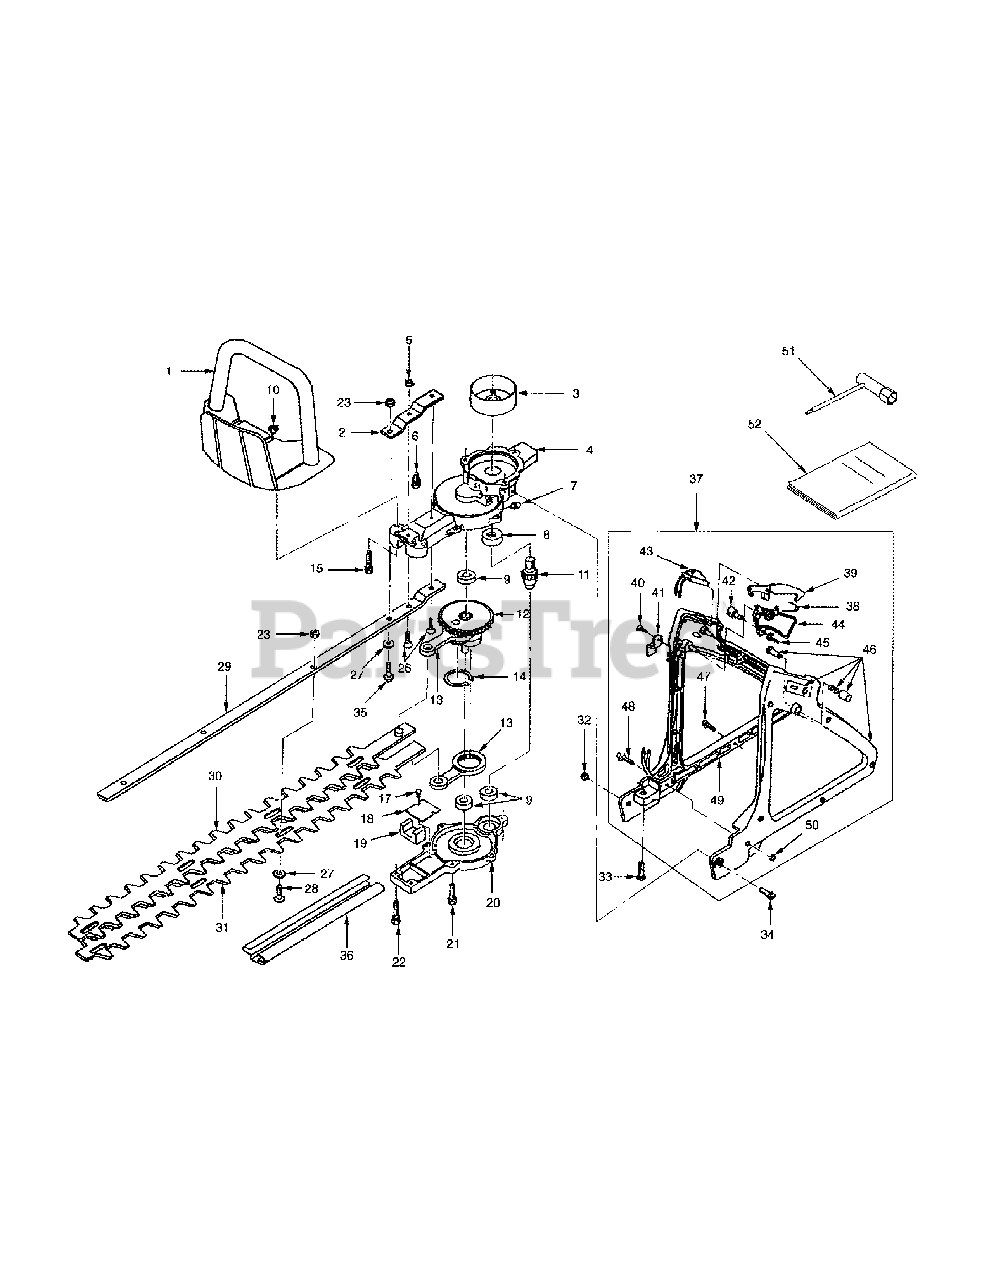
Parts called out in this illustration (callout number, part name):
3	Drum, Clutch
7	Nipples, Grease
8	Bearing, Ball, 6001
9	Bearing, Ball, 6082
11	Gear, Pinion
14	Snap Ring, S-26
26	Screw, M5x20
36	Cover, Balde
37	Handle Assembly
40	Screw, M4x10
42	Piece, Set
43	Switch, Stop
47	Screw, M4x16
48	Screw, M4x30
51	Wrench, Spanner Box 19
52	Manual, Operator's
